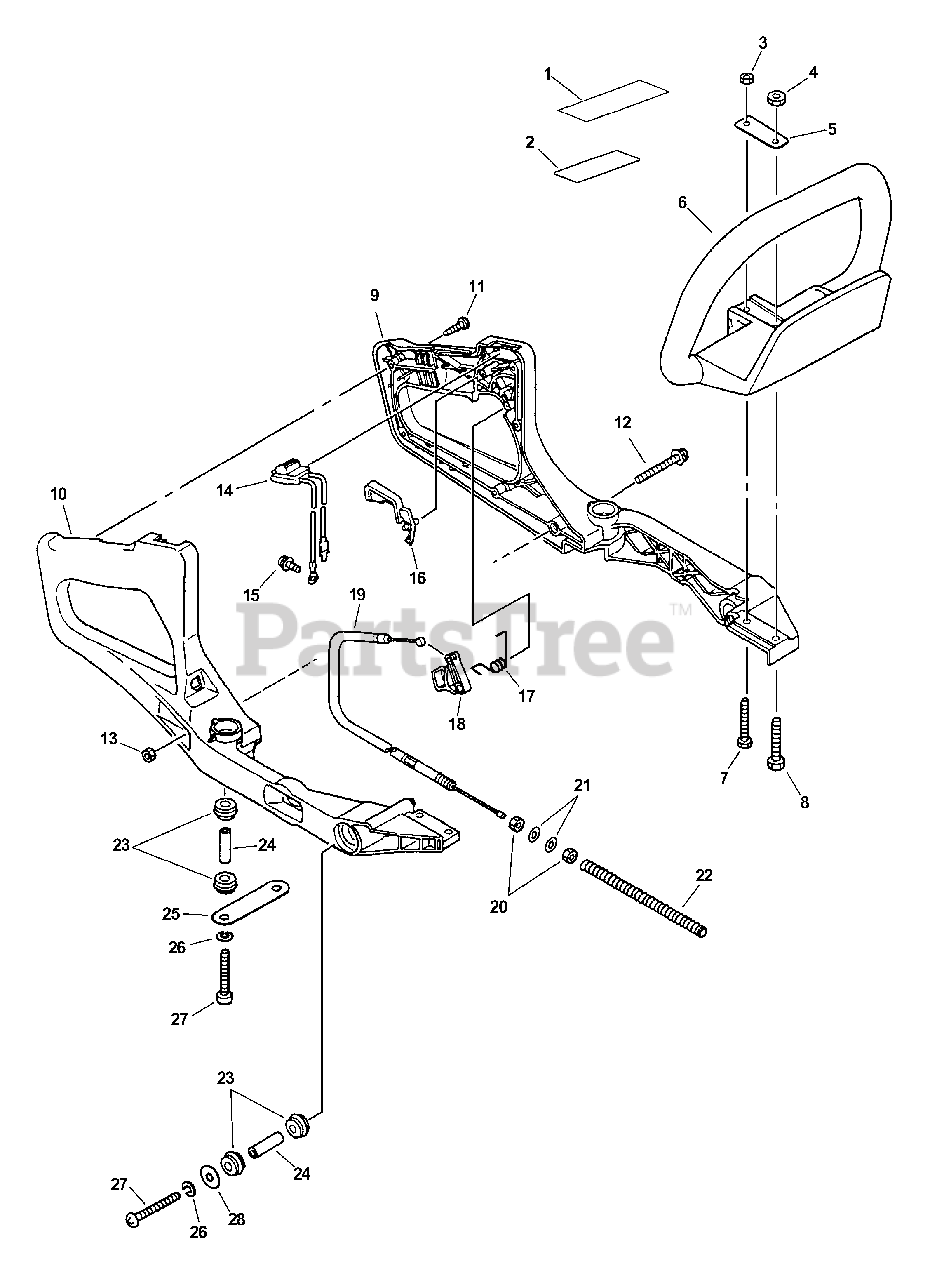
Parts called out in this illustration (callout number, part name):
1	LABEL - CAUTION
2	LABEL - CAUTION
4	LOCKNUT - 6
6	HANDLE - FRONT
7	BOLT - 5X35
8	BOLT - 6X32
9	HANDLE, REAR - LEFT
10	HANDLE, REAR - RIGHT
11	SCREW - 4X25
12	SCREW - 5X64
14	IGNITION SWITCH ASSY
15	SCREW - 5X10
16	LOCKOUT, THROTTLE
17	SPRING, LOCKOUT LEVER
18	TRIGGER, THROTTLE
19	CABLE, THROTTLE
21	WASHER - 6
24	SPACER
25	PLATE
26	LOCKWASHER - 5
27	SCREW - 5X40
